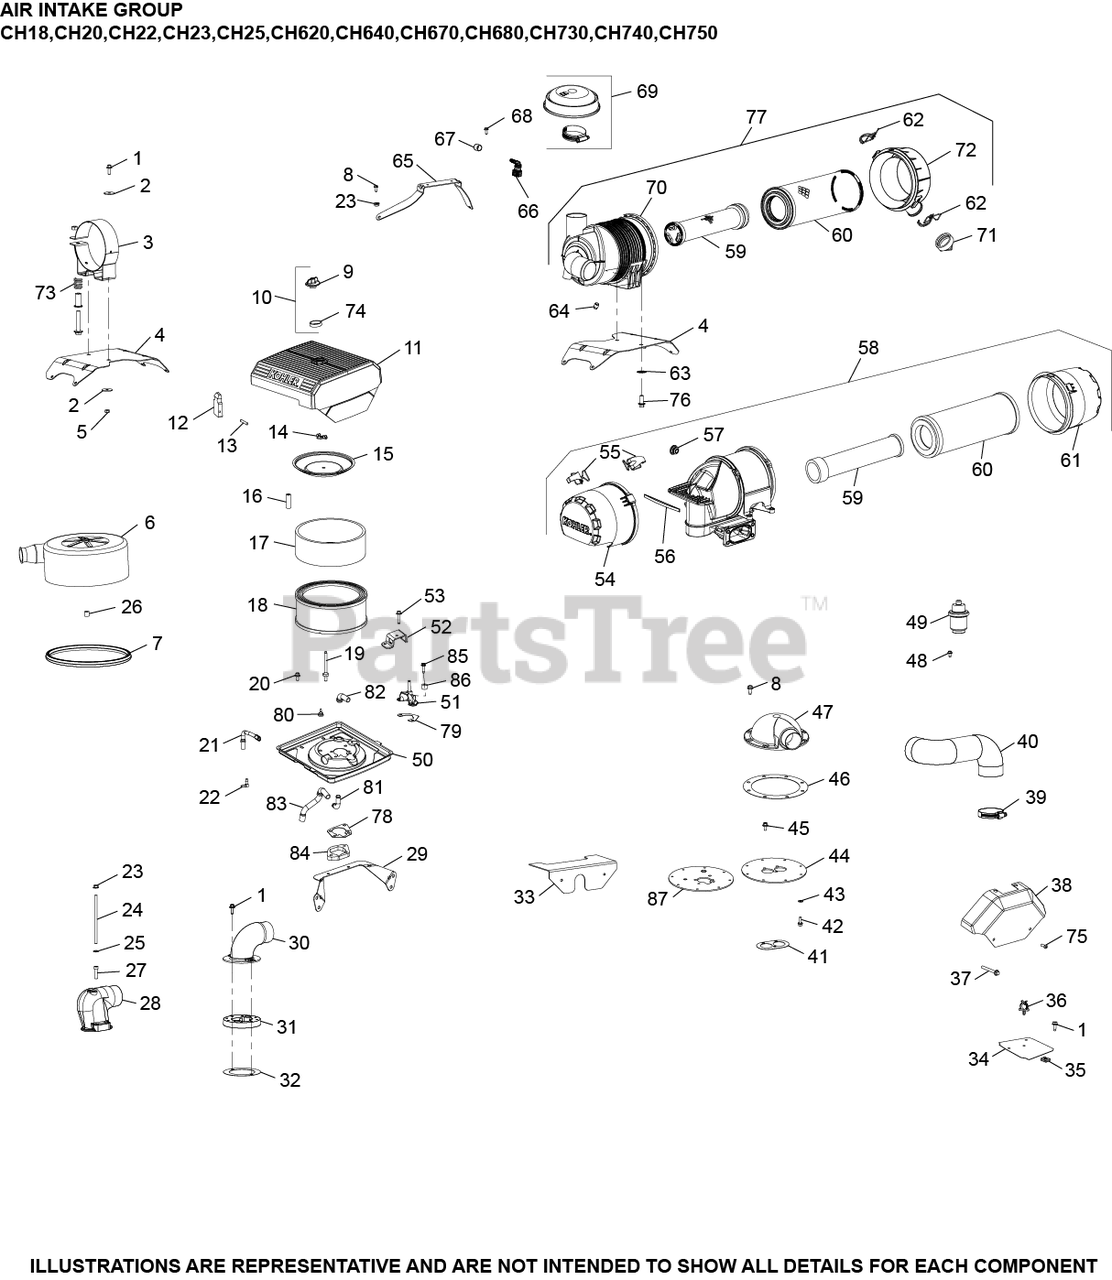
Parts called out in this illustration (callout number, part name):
4	BRACKET, AIR CLEANER
33	SHIELD, DEBRIS
39	CLAMP, HOSE-USE 25 237 21-S
40	HOSE, AIR CLEANER
59	ELEMENT, AIR FILTER - SAFETY
60	ELEMENT, AIR FILTER - PRIMARY
62	CLIP - USE 62 154 07-S
63	WASHER,INT EXT TOOTH LOCK 5/16"
64	PLUG, PIPE
69	HOOD, INLET
70	HOUSING, HEAVY DUTY A/C
71	VALVE, DUST EJECTOR
72	COVER ASSEMBLY, AIR CLEANER
76	SCREW, FLG M8X1.25X20
77	AIR CLEANER, CANISTER
